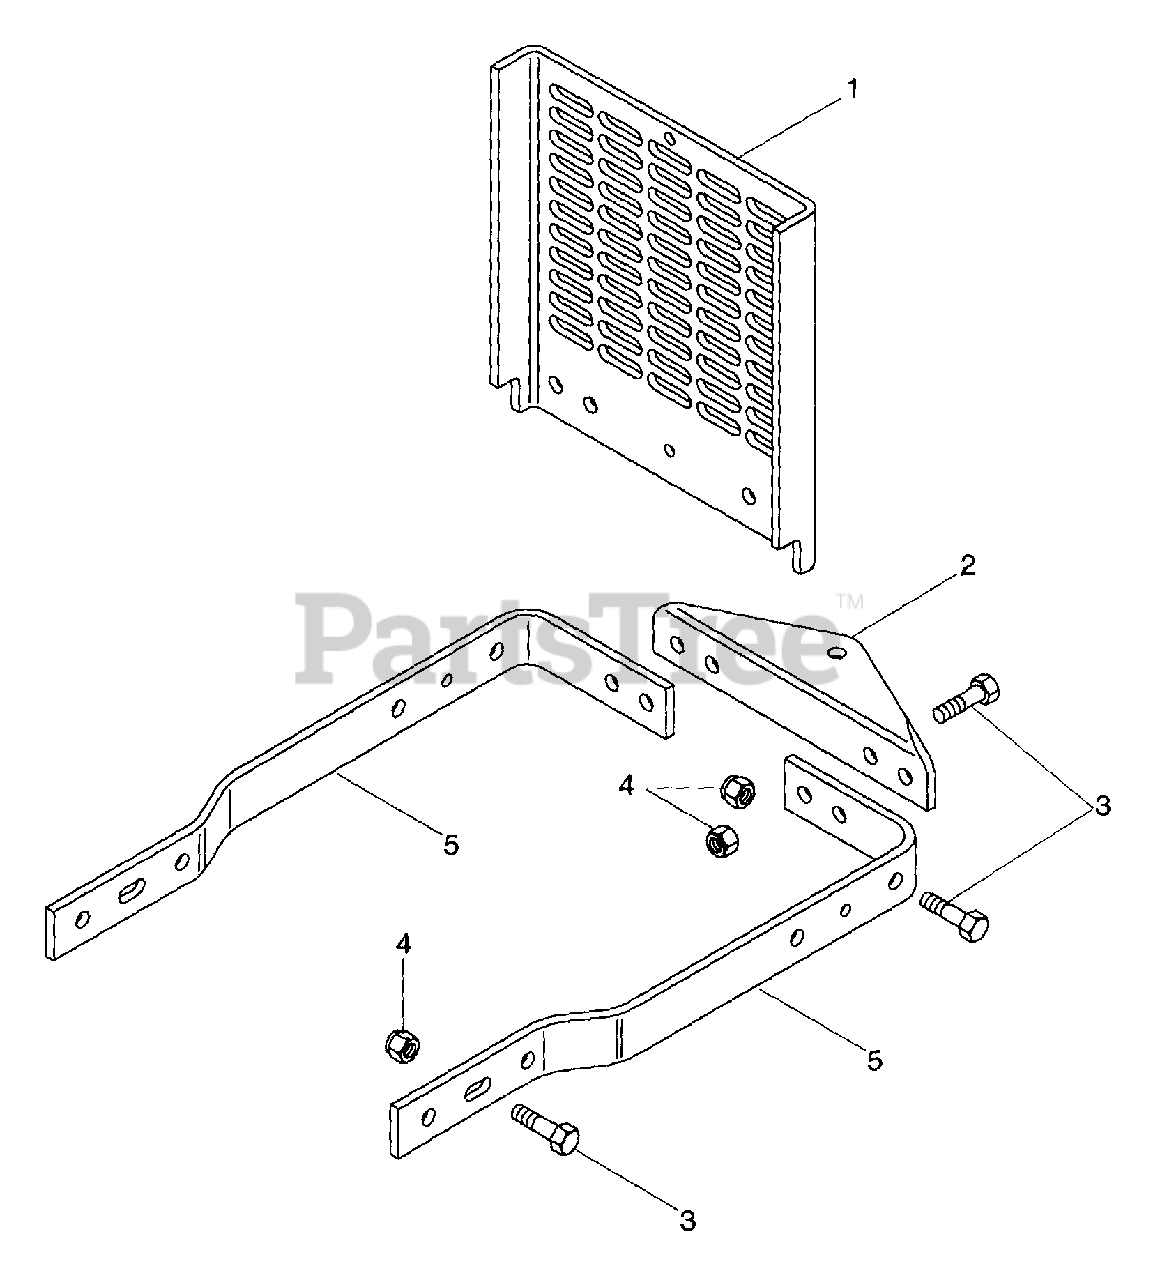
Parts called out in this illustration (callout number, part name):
1	Guard, Engine
2	Plate, Hitch
3	Bolt-Hex .50-13 x 1.75
4	Nut-Locking-Nylon .50-13 Grade 5
5	Arm, Rear Hitch
